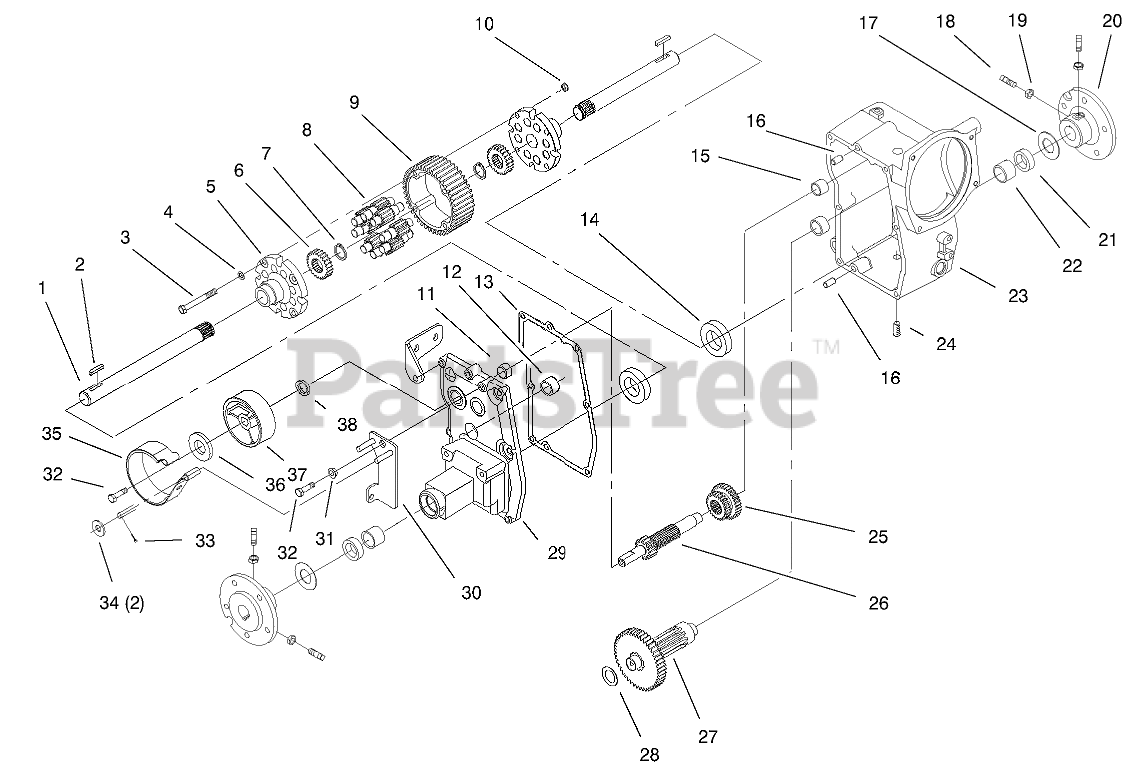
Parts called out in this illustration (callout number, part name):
1	AXLE-REAR
3	BOLT-HEX
4	WASHER
5	END CAP-DIFFERENTIAL
6	GEAR-AXLE DIFFERENTIAL
7	RING-SNAP
8	GEAR-PINION, 11T
9	GEAR-DIFFERENTIAL RING, 43T
11	BEARING-NEEDLE
12	BEARING-NEEDLE
13	GASKET-CASE
14	BEARING-BALL
15	BEARING-NEEDLE
16	PIN-LOCATING
17	WASHER-THRUST
18	SCREW-SET, SQH
19	NUT-JAM
20	HUB-WHEEL
21	SEAL-OIL
22	BEARING
23	CASE-LH
24	PLUG-PIPE
25	GEAR-SLIDING
26	SHAFT-BRAKE
27	GEAR ASM
28	WASHER-THRUST
29	CASE-RH
30	Arm-PIVOT, Brake
31	CAM-SPACER
32	SCREW-HH, LOCK
33	PIN-COTTER
34	WASHER-FLAT
35	BAND-BRAKE
36	WASHER
37	DRUM-BRAKE
38	SEAL-OIL
